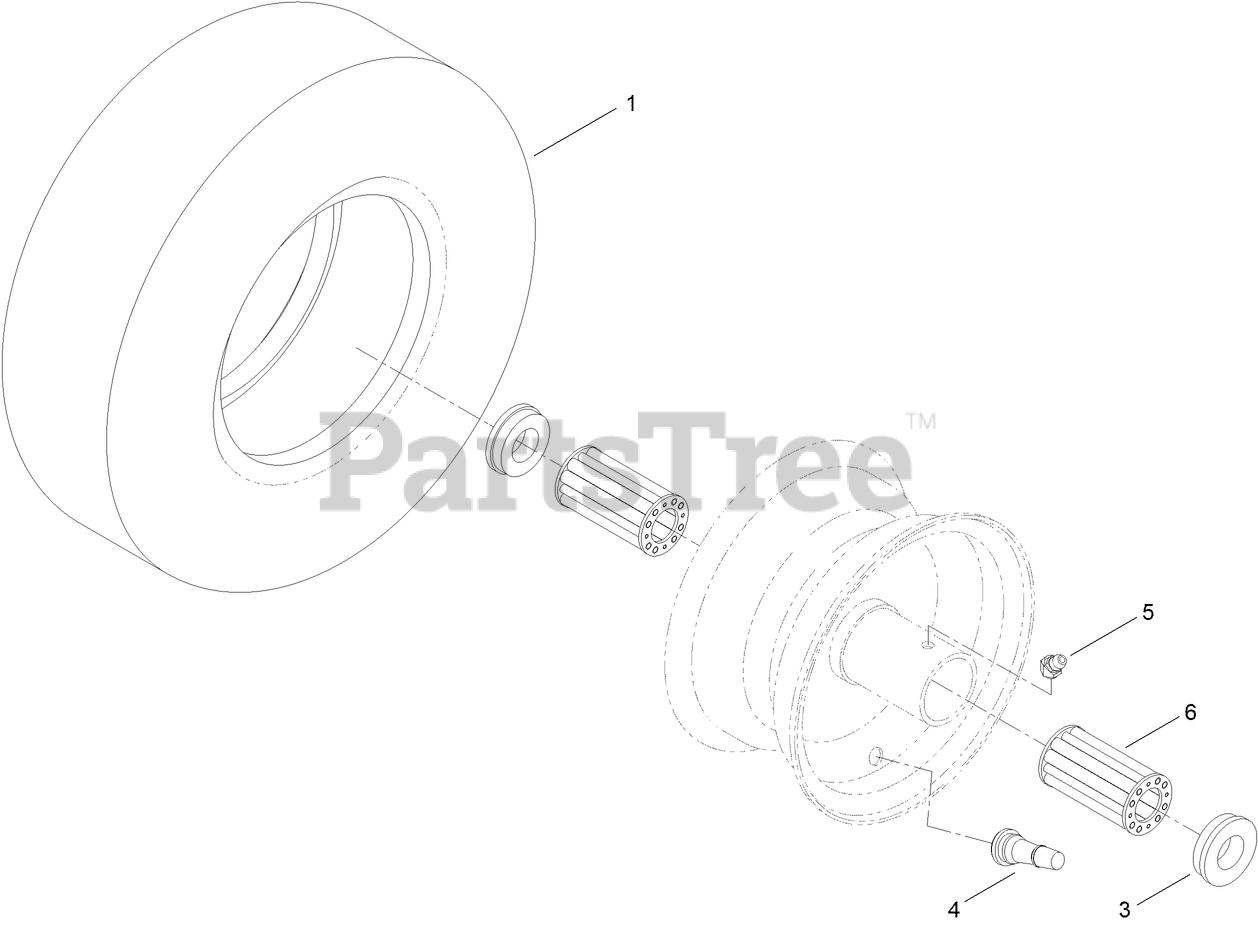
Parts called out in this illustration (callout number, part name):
4	VALVE
5	FITTING-ZERK
6	BEARING
